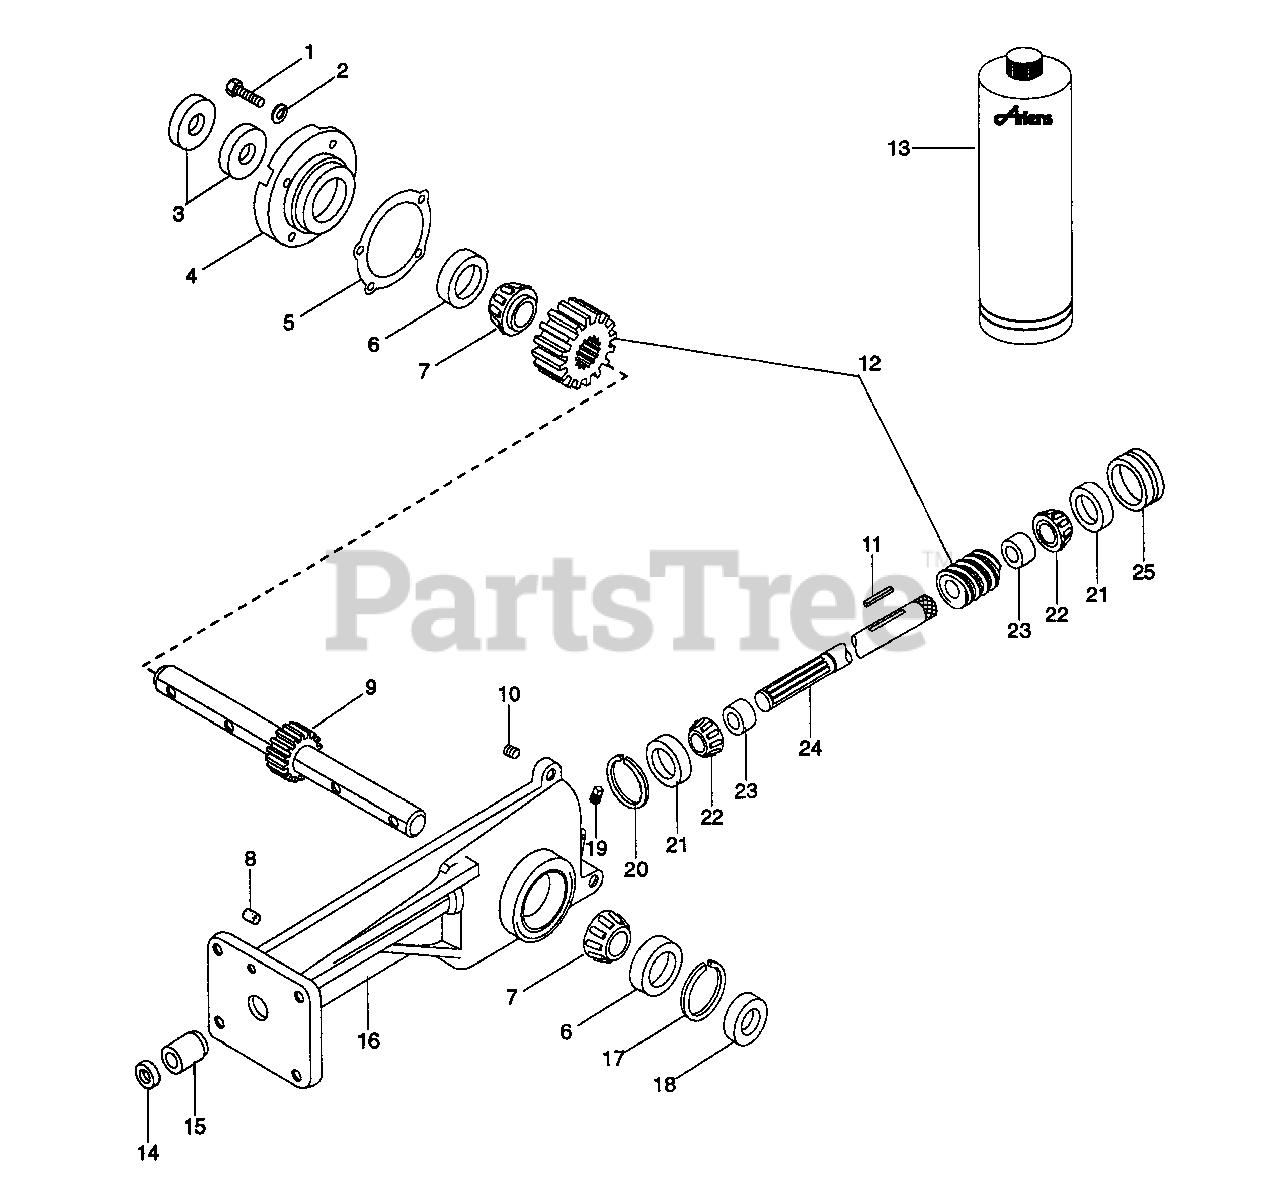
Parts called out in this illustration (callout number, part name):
1	BLT-HEX .38-16X1.00 PL GR5
2	WSHR-LK .375X.115 HVY PL
3	SEAL 1.000X1.785X.250
3	SEAL 1.250X2.00X.250
4	BEARING FLANGE
5	SERVICE KIT
6	BRG-CUP1.980X.420
6	BRG-CUP 2.328X.465
7	BRG-CONE 1.0X.58
7	BRG-CONE 1.25X.66
8	BREATHER
9	TINE SHAFT
10	SCR-SET .25-20X.25 SKHCUPNY OH
11	KEY-SQ .188X1.0X.188 SAE 8630
12	WORM & WORM GEAR SERVICE ASSY
12	WORM AND WORM GEAR ASSEMBLY
13	ARIENS 16 OZ.BOTTLE OF L2 LUBE
14	SEAL .750X1.000X.125
15	BRG-NEEDLE .750X1.0X.62
16	TILLER GEARCASE - C.I.
17	RG-RTNG-INT 1.969X.062
18	SEAL 1.000X1.980X.375
18	SEAL 1.250X2.00X.250
19	PIPE PLUG
20	RG-RTNG-INT 1.781X.062
21	BRG-CUP 1.781X.475
22	BRG-CONE .750X.61
23	BSHG, SPCR .755X1.12X.50 PM
24	WORM SHAFT
25	ADJUSTMENT PLUG
